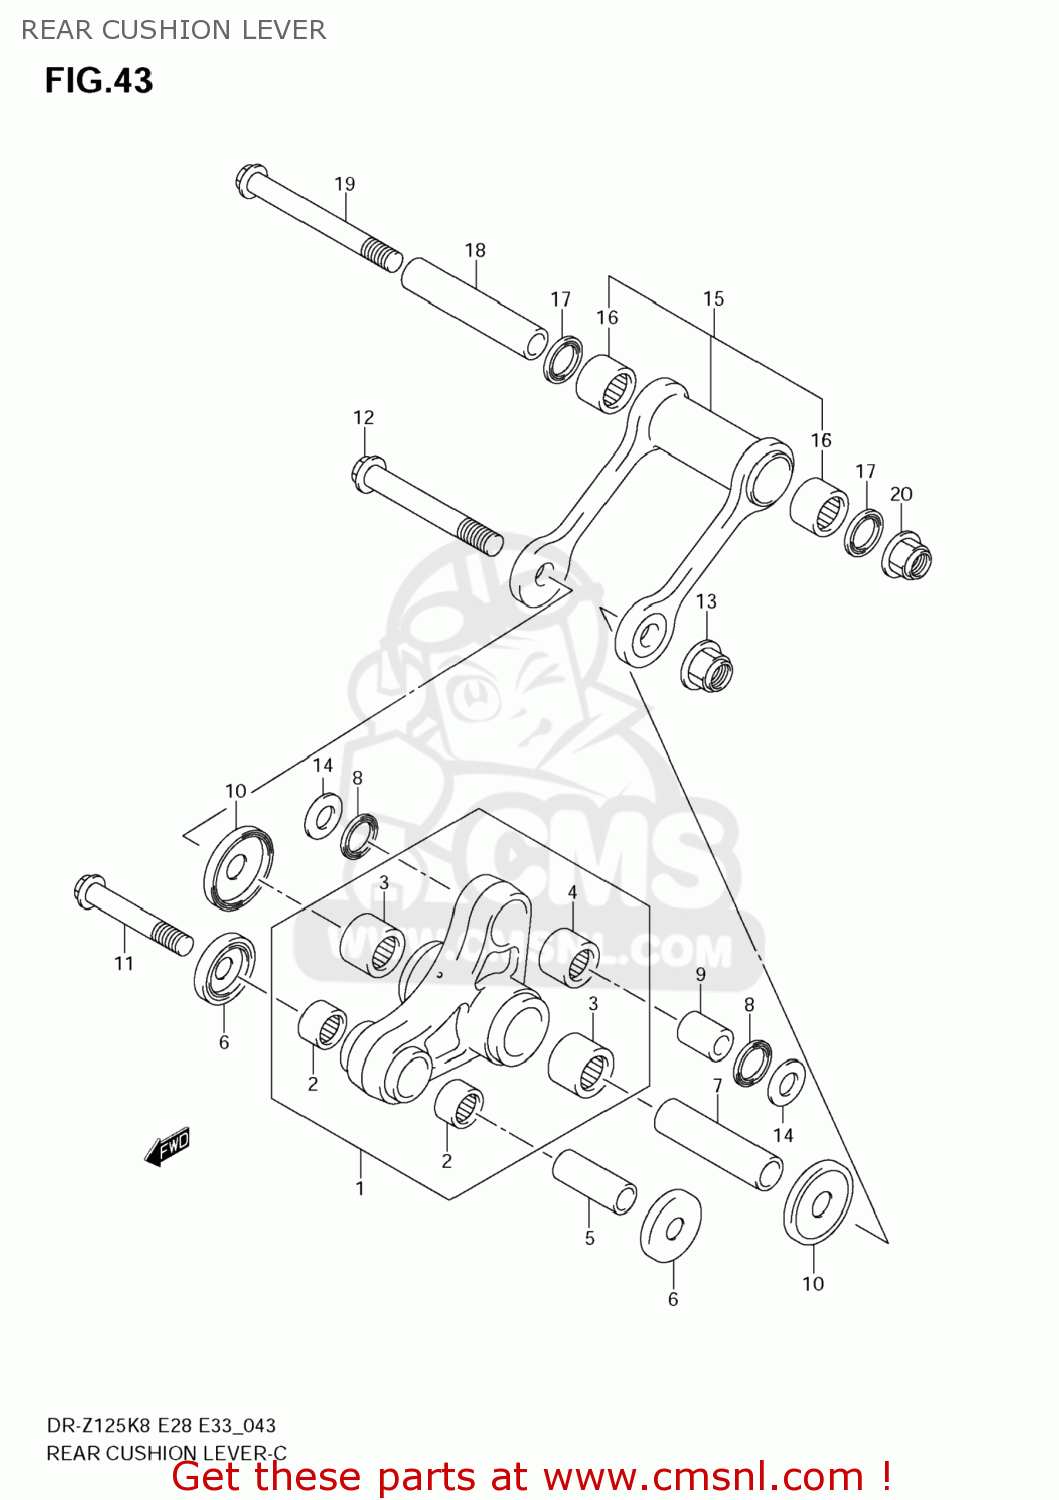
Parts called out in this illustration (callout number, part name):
1	LEVER SET,RR CUSHION
2	BEARING(14X20X12)
3	BEARING(17X24X20)
4	BEARING(16X22X12)
5	SPACER,RR CUSHION LEVER FR
6	SEAL,RR CUSHION LEVER FR DUST
7	SPACER(12X17X60)
8	SEAL,OIL(16X22X2.5)
9	SPACER,RR CUSHION LEVER RR
10	SEAL,RR CUSHION LEVER FR DUST
11	BOLT,RR CUSHION LEVER FR
12	BOLT,RR CUSHION LEVER CTR
13	NUT
14	WASHER,THRUST LVR CUSHION RR
15	ROD SET,RR CUSHION
16	BEARING(17X24X20)
17	SEAL,OIL(17X24X3)
18	SPACER,RR CUSHION ROD
19	BOLT,RR CUSHION ROD
20	NUT
